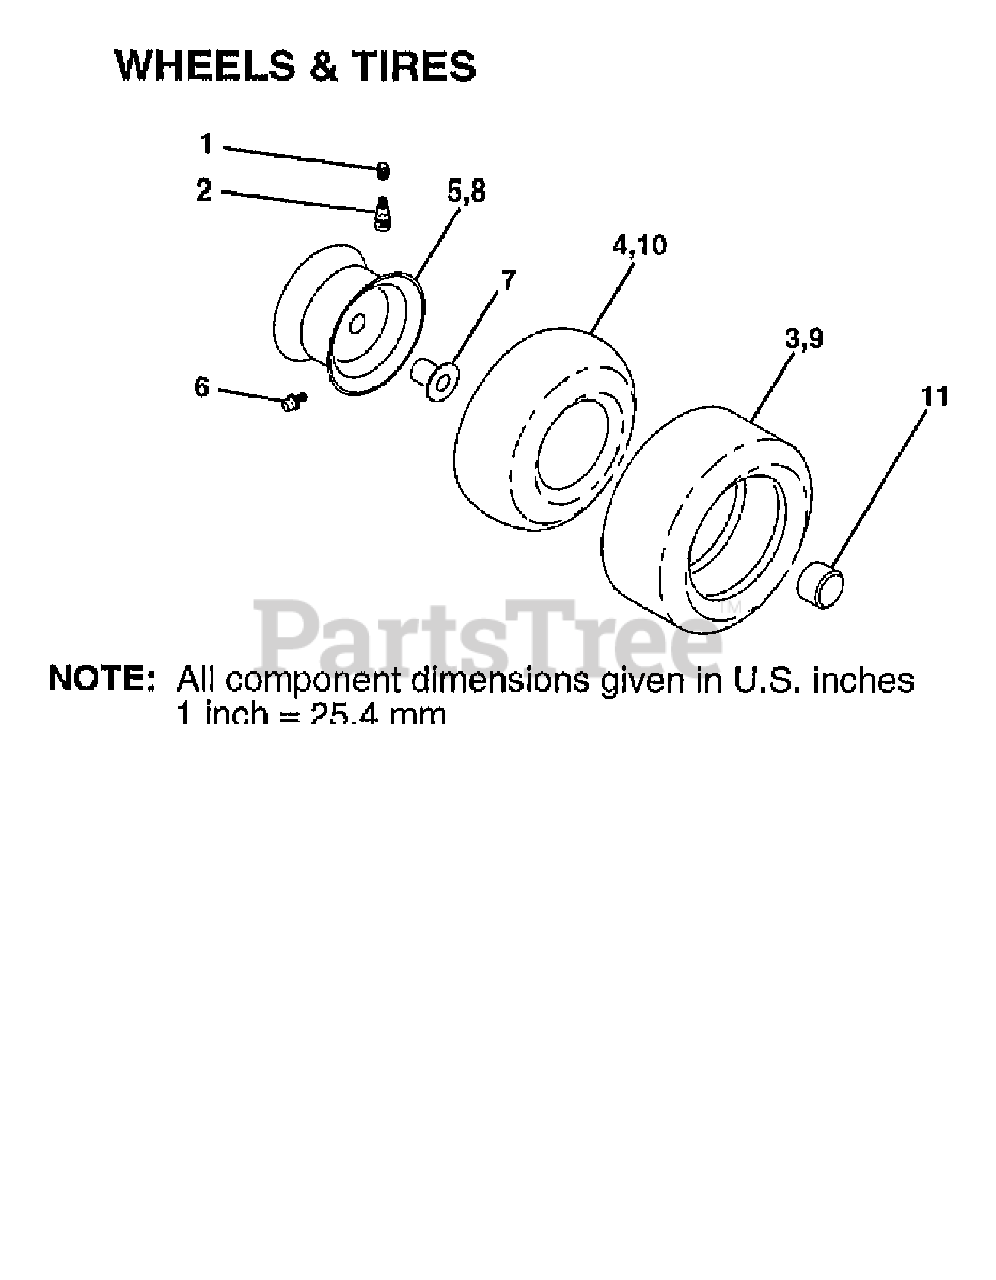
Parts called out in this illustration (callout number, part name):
1	VALVE CAP
2	VALVE STEM LT
3	TIRE HEAVY DUTY
4	TUBE.5.3/4.5/6
5	RIM.ASM.6".FRONT.SILVER
6	FITTING LT
7	BEARING T
8	RIM 8" SILVER
9	TIRE 20X8-8 TURF SAVER
10	TUBE - UNIVERSAL FOR 8" RIM
11	CAP.HUB.FRONT.LT.BLACK
